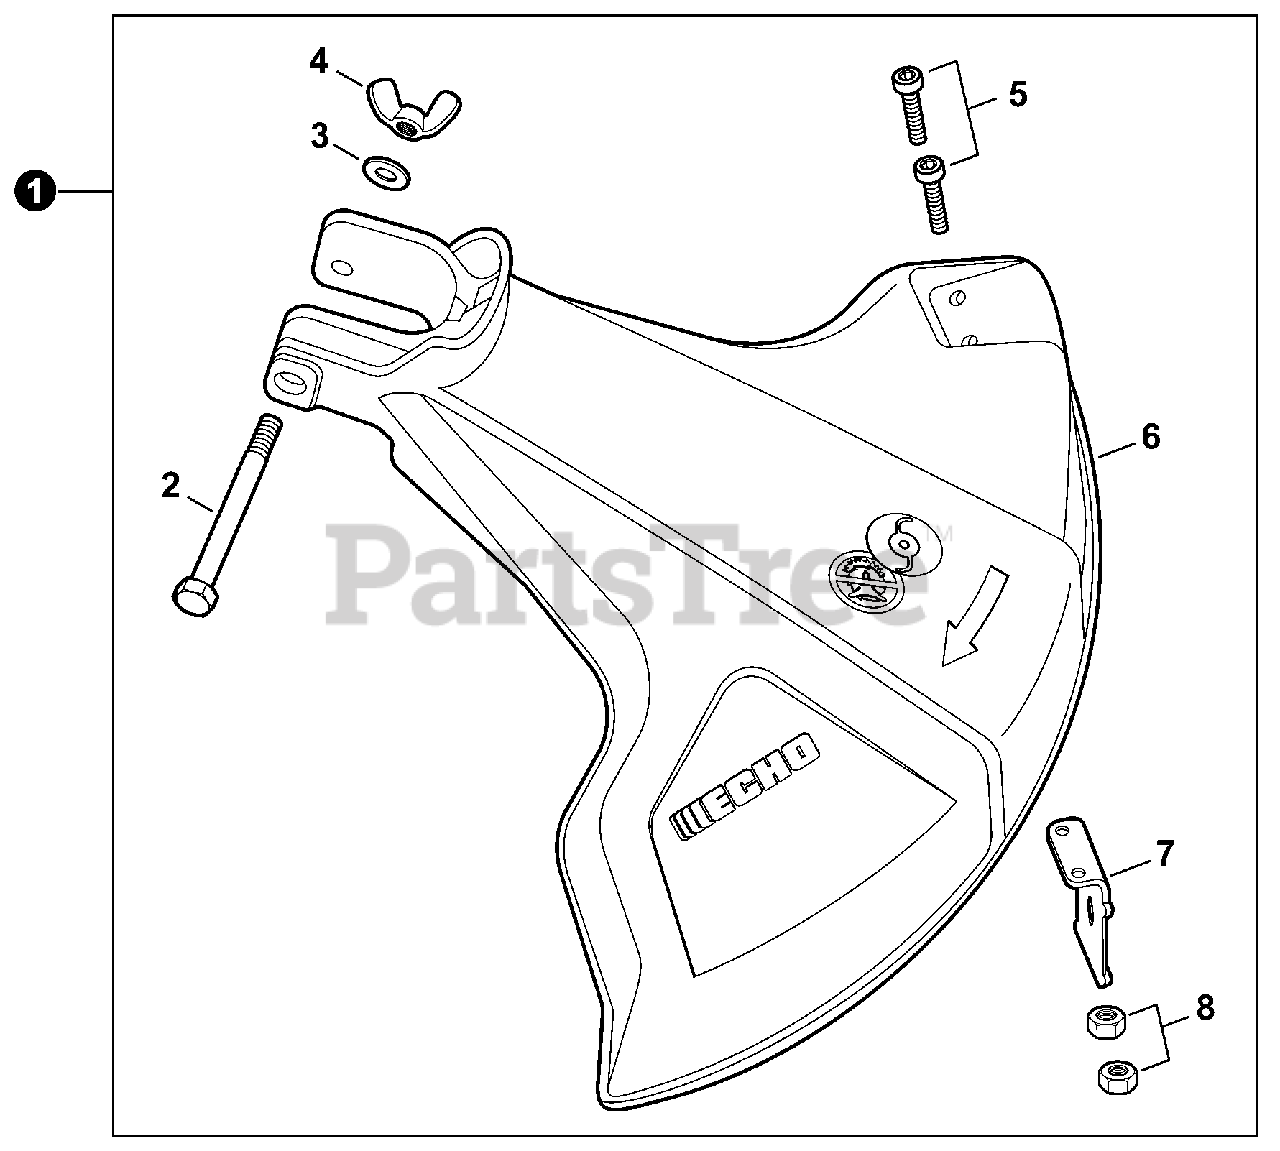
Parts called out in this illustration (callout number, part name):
1	SHIELD ASSY, DEBRIS
2	BOLT 1/4"-20x2"
3	WASHER, 1/4"
4	NUT, WING 1/4"-20
5	BOLT, TORX 5x12
6	SHIELD, DEBRIS
7	CUTTER, LINE
